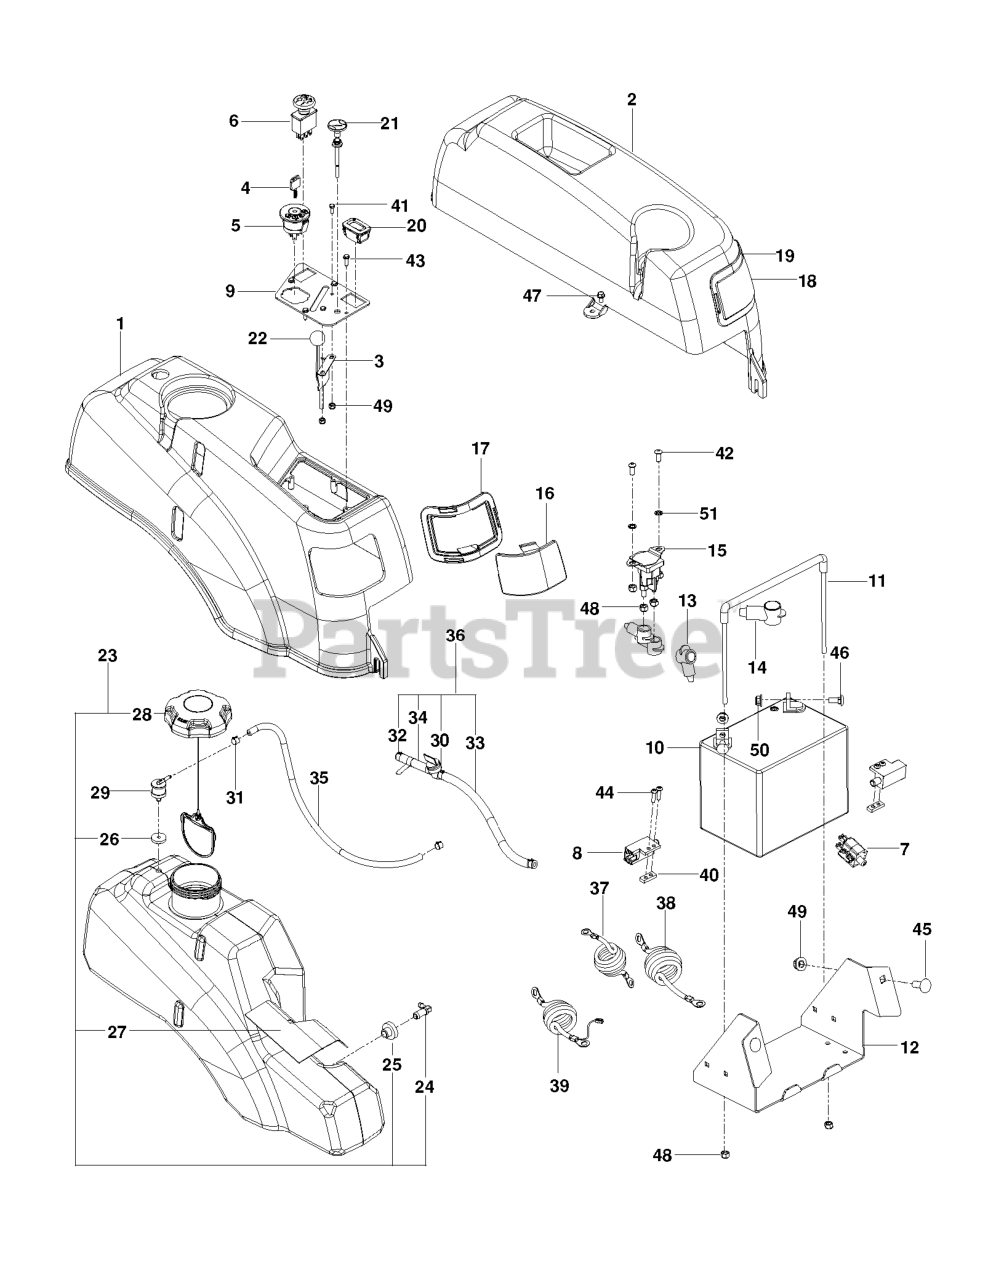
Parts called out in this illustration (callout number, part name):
1	FENDER RT, GRAY
2	FENDER, LT
3	THROTTLE CABLE
4	KEY
5	RP IGNITION SWITCH
6	SWITCH.PTO
7	SWITCH, BRAKE 3P
8	SWITCH INTERLOCKT
9	CONSOLE.PLATE.BLACK
10	BATTERY, 12 V 330 AMP
11	BATTERY TIE DOWN ASSEMBLY
12	BOX, BATTERY, BLACK
13	TERMINAL COVER-SM
16	LENS, COLORED RIGHT
17	RT HEADLIGHT RIM GREY
18	LENS, COLORED LEFT
19	LEFT HEADLIGHT RIM GREY
20	HOUR METER
21	CHOKE CABLE
22	KNOB.ROUND.BALL.BLACK
23	TANK.FUEL.ASSEMBLY.LARGE
24	STEM, FUEL TANK
25	RUBBER GROMMET
26	GROMMET, CHECK VALVE
27	SHIELD, HEAT
28	CAP, FUEL
29	VALVE.FUEL.CHECK
30	FUEL VALVE
31	CLAMP, HOSE
32	HOSE CLAMP
33	GAS LINE 10"
34	FUEL LINE 3"
35	HOSE, FUEL, 3/16" X 20"
36	FUEL LINE ASSY
37	CABLE POSITIVE, LONG
38	BATTERY CABLE, NEGATIVE
39	CABLE POSITIVE LONG W/LEAD
40	TAPPED PLATE
41	HCS #10-24 X 1/2
42	SCR 1/4-20 X 5/8 BTN SKT HD ZD
43	SCR #10-12X3/4 HEX WAS HD ZD
44	SCR #10-24 X .75 SKT HD BLK
46	RP BOLT 5/16-18 X3/4 ZN/YEL GR
47	BOLT 1/4-20 X 1/2 HWST
48	JAM NUT 1/4C (2 2 PW01)
49	NUT 10-24 NYLOC
50	5/16-18 NYLOC FLANGE NUT
51	WASHER 1/4 INT TOOTH
